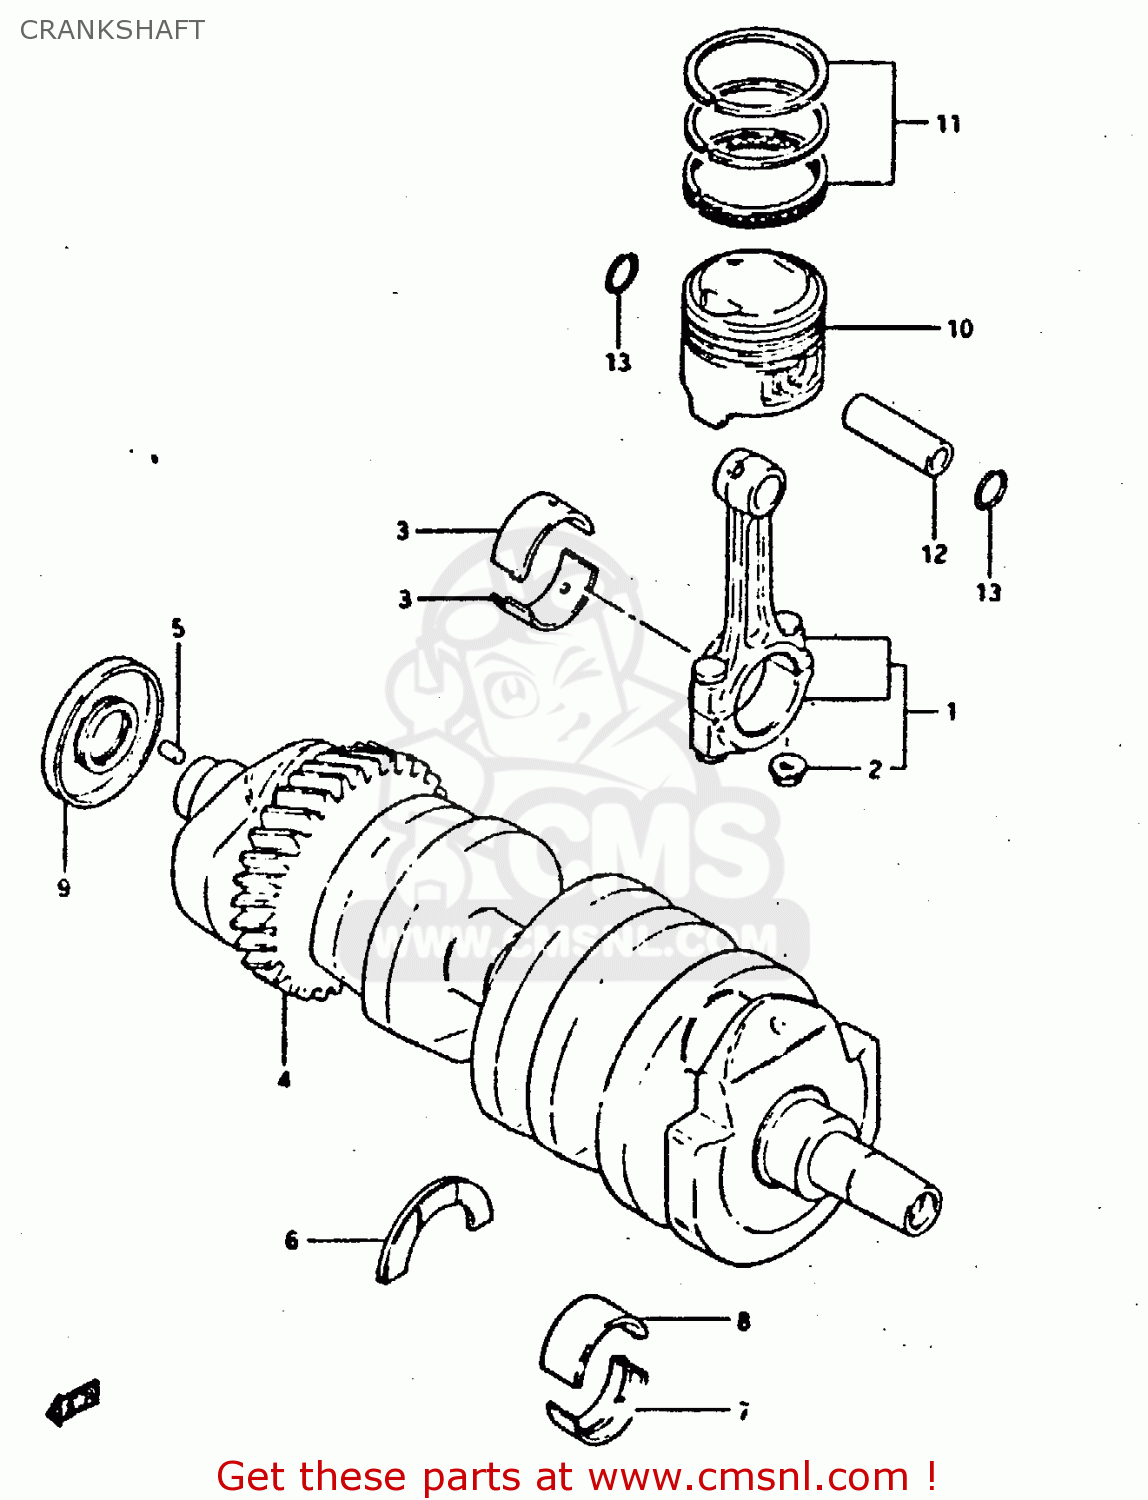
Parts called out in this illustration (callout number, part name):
1	CONNECTING ROD ASSEMBLY
2	NUT
3	BEARING,CRANK PIN
4	CRANKSHAFT
5	PIN
6	PLATE,CRANK THRUST
7	METAL CRANKSHAFT (YELLOW)
8	METAL CRANKSHAFT (BROWN)
9	OIL SEAL
10	PISTON (62.00MM)
11	RING SET,PISTON
12	PIN,PISTON
13	CIRCLIP
